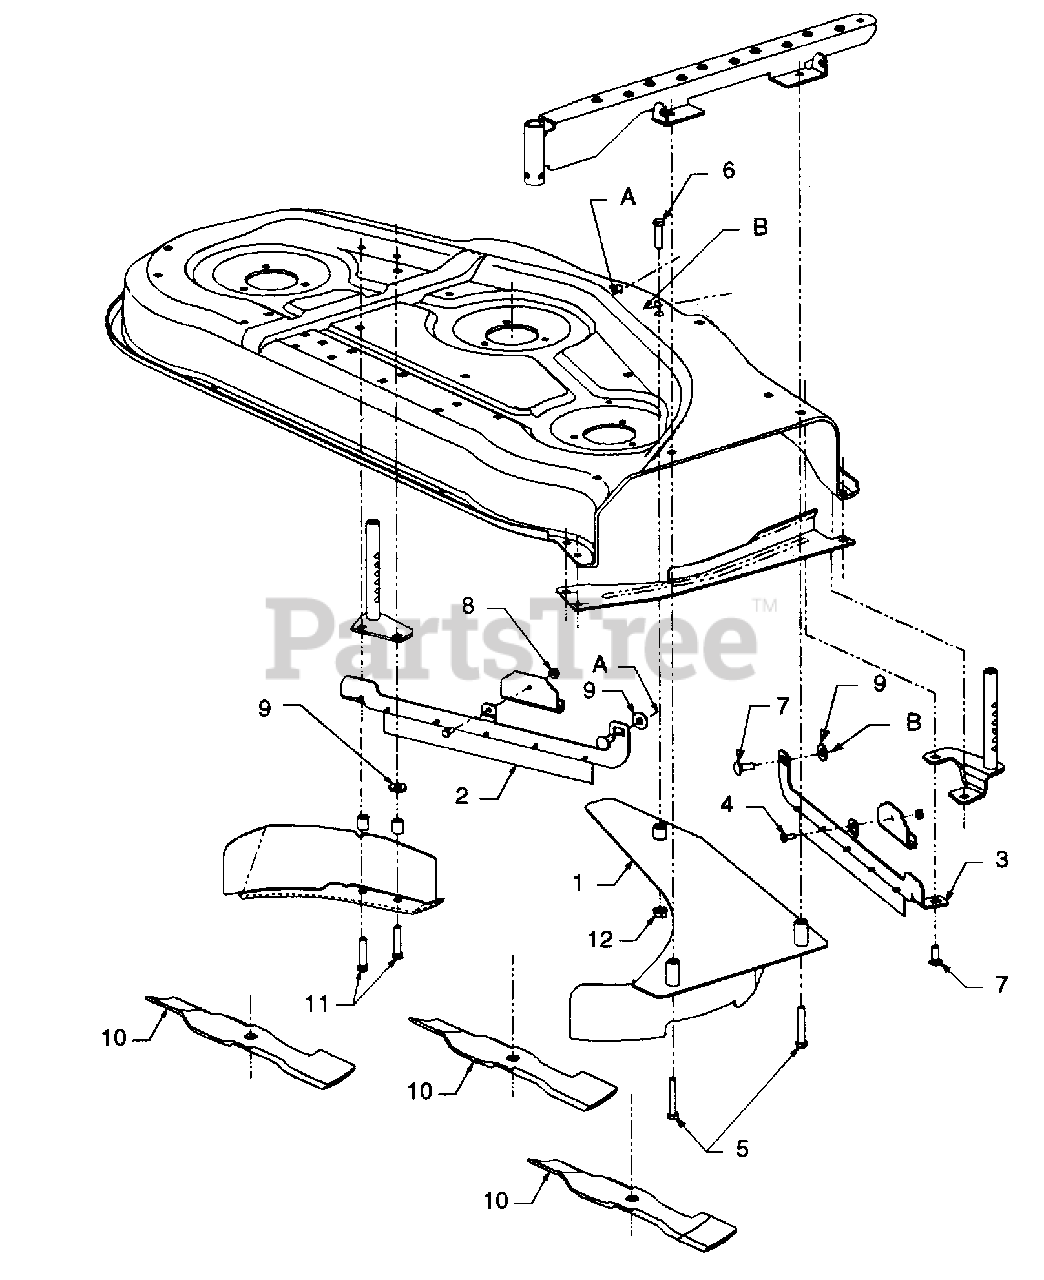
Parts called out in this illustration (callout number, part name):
4	Screw, Hex Cap, 1/4-20 X .62 GR5
5	Screw, Hex Cap, 3/8-16 X 2-1/4 GR5
6	Screw, Hex Cap, 3/8-16 X 1.50 GR5
7	Bolt, Carriage, 3/8-16 X 1.0 GR5
8	Nut, Hex Flange Lock, 1/4-20
9	Washer, Flat, .406 X 1.0 X .105
10	Blade, Mulching, 16.5 Lg
11	Screw, Hex Cap, 3/8-16 X 1-3/4 GR5
12	Nut, Hex Flange Lock 3/8-16
